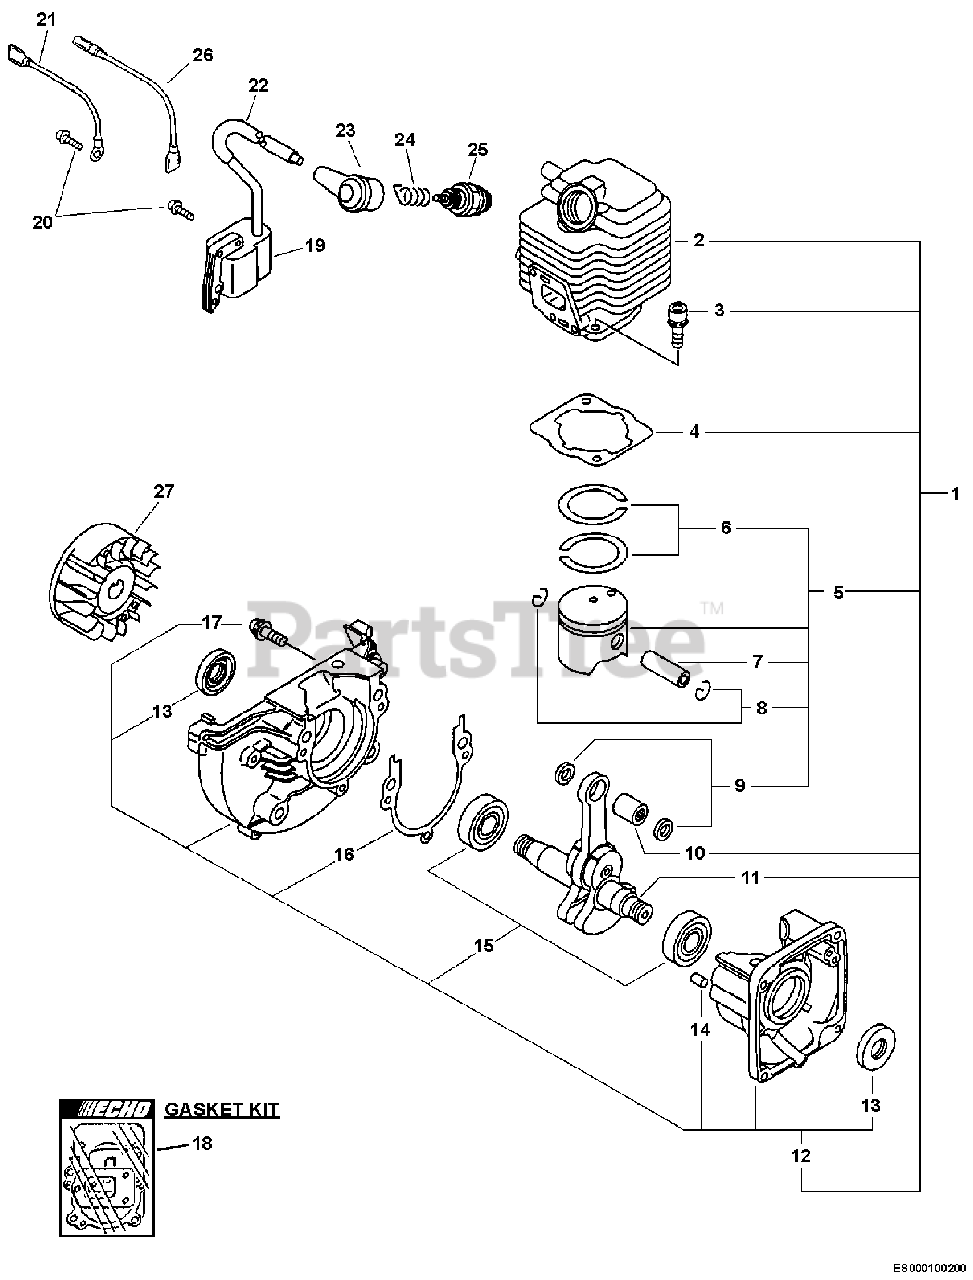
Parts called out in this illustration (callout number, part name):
1	SHORT BLOCK
2	CYLINDER
3	BOLT 5×22
4	GASKET, CYLINDER
5	PISTON KIT
6	RING, PISTON
7	PIN, PISTON 8
8	RING, SNAP
9	WASHER, THRUST
10	BEARING, NEEDLE
11	CRANKSHAFT ASSY
12	CRANKCASE KIT
13	SEAL, OIL 12
14	PIN, LOCATING 4
15	BEARING, BALL - 6201 C3
16	GASKET, CRANKCASE
17	BOLT 5×28
18	GASKET KIT
19	COIL, IGNITION
20	SCREW 4×22
21	LEAD - IGNITION
23	CAP, SPARK PLUG
24	TERMINAL, SPARK PLUG
25	SPARK PLUG - BPM-7Y
26	LEAD
27	FLYWHEEL
